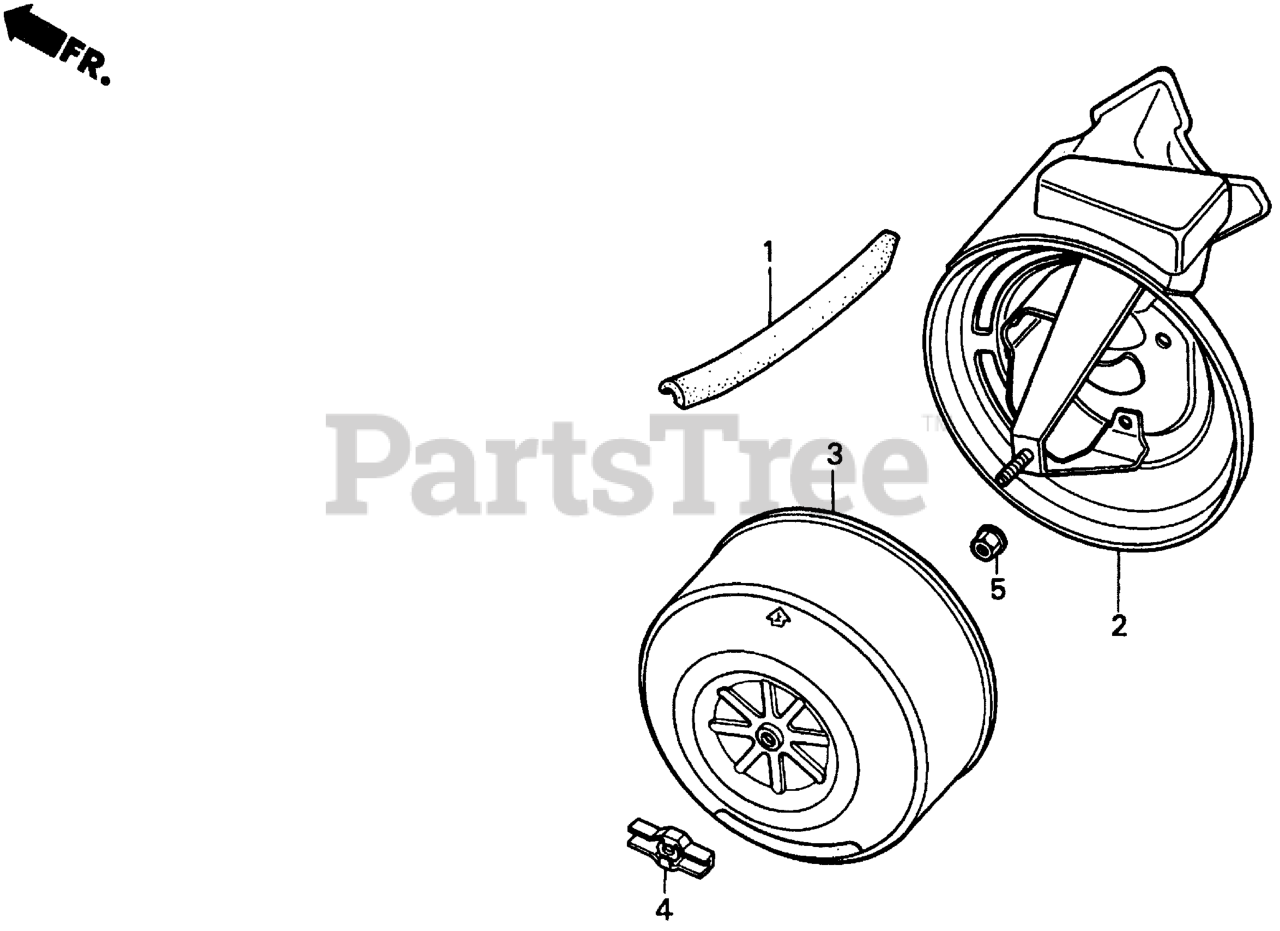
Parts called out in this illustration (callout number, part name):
1	TUBE, BREATHER
2	HOUSING, AIR CLEANER
3	COVER, AIR CLEANER
4	WINGNUT, AIR CLEANER COVER
5	NUT, FLANGE (6MM)
